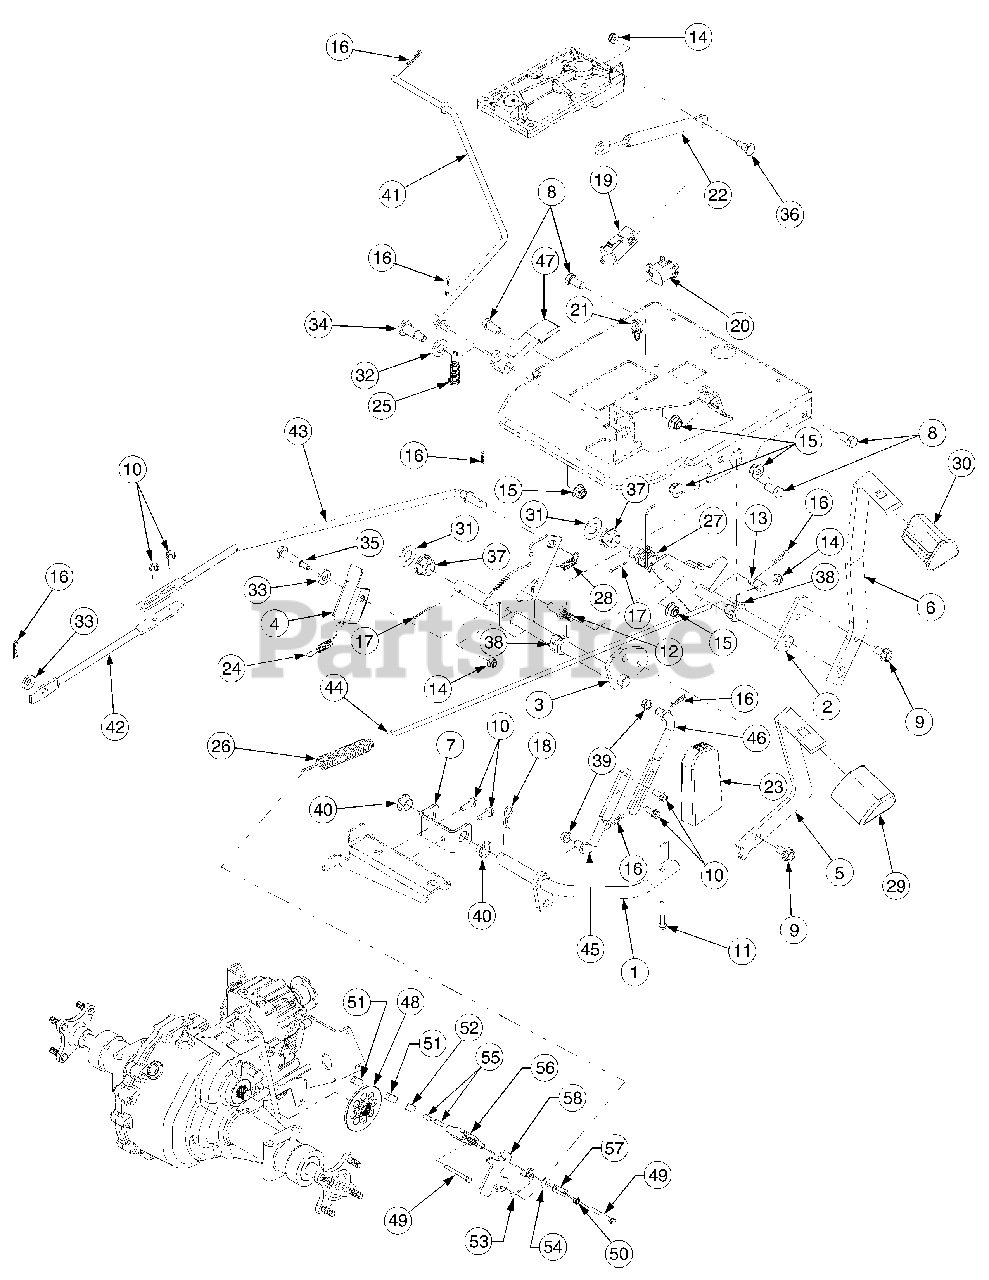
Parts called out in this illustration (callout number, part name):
3	Shaft Assy, Forward/Reverse
8	Screw, Hex Cap, 3/8-16 x 1.0 GR5
9	Screw, Hex Wash Hd Tapp 3/8-16x .75
10	Screw, Hex Wash Hd Tapp 1/4-20x .75
11	Screw, Truss Mach, #12 x 1.5
12	Pin, 3/8-16 x 1.0
13	Ferrule, Adjustment, 1/4-20 Thrd
14	Nut, Hex Flange Lock, 1/4-20
15	Nut, Hex Flange Lock, 3/8-16
16	Pin, Internal Cotter, 5/16 Dia x 1.12
17	Pin, Cotter, 3/32 x 1.0
18	Pin, Internal Cotter, 3/8 Dia x 1.62
19	Switch, Interlock (Brake)
20	Switch, Snap Mount (Reverse)
21	Clip, Cable Retainer
22	Cylinder, Damper, .59 OD x 7.84 Lg
23	Pedal, Reverse
24	Spring, Extension, .38 OD x 2.1
25	Sping, Extension
26	Spring, Extension
27	Spring, Torsion
28	Spring, Extension, .375 OD x 1.44
29	Pad, Forward Foot Control
30	Pad, Brake Foot
31	Washer, Flat, .64 x 1.24 x .06 HT
32	Washer, Flat, .51 x 1.0 x .125
33	Washer, Flat, .407 x .812 x .135 HT
34	Shoulder Bolt, .50 OD x .840
35	Screw, Shoulder, .374 x 1.375
36	Screw, Shoulder, .375 x .380:1/4-20
37	Bearing, Hex Flange
38	Bearing, Hex Flange Split
39	Bearing, Flange, .375 x .58 x .25
40	Bearing, Flange, .625 x .938 x .344
41	Rod, Cruise
42	Rod, Rear F/R Control
43	Rod, Front F/R Control
44	Rod, Brake
45	Rod, Rear Connecting
46	Rod, Front Connecting
47	Latch, Cruise
48	Disc, Brake
49	Screw, Hex Wash Hd, Tapp, 1/4-20 x 2.375
50	Nut, Hex Nylon Lock, 5/16-24
51	Pad, Brake
52	Plate, Puck
53	Spring, Torsion
54	Washer, Flat, .343 x .88 x .062
55	Pin, Brake Actuating
56	Yoke, Brake
57	Bracket, Brake Anti Rotation
58	Arm, Brake Actuator
